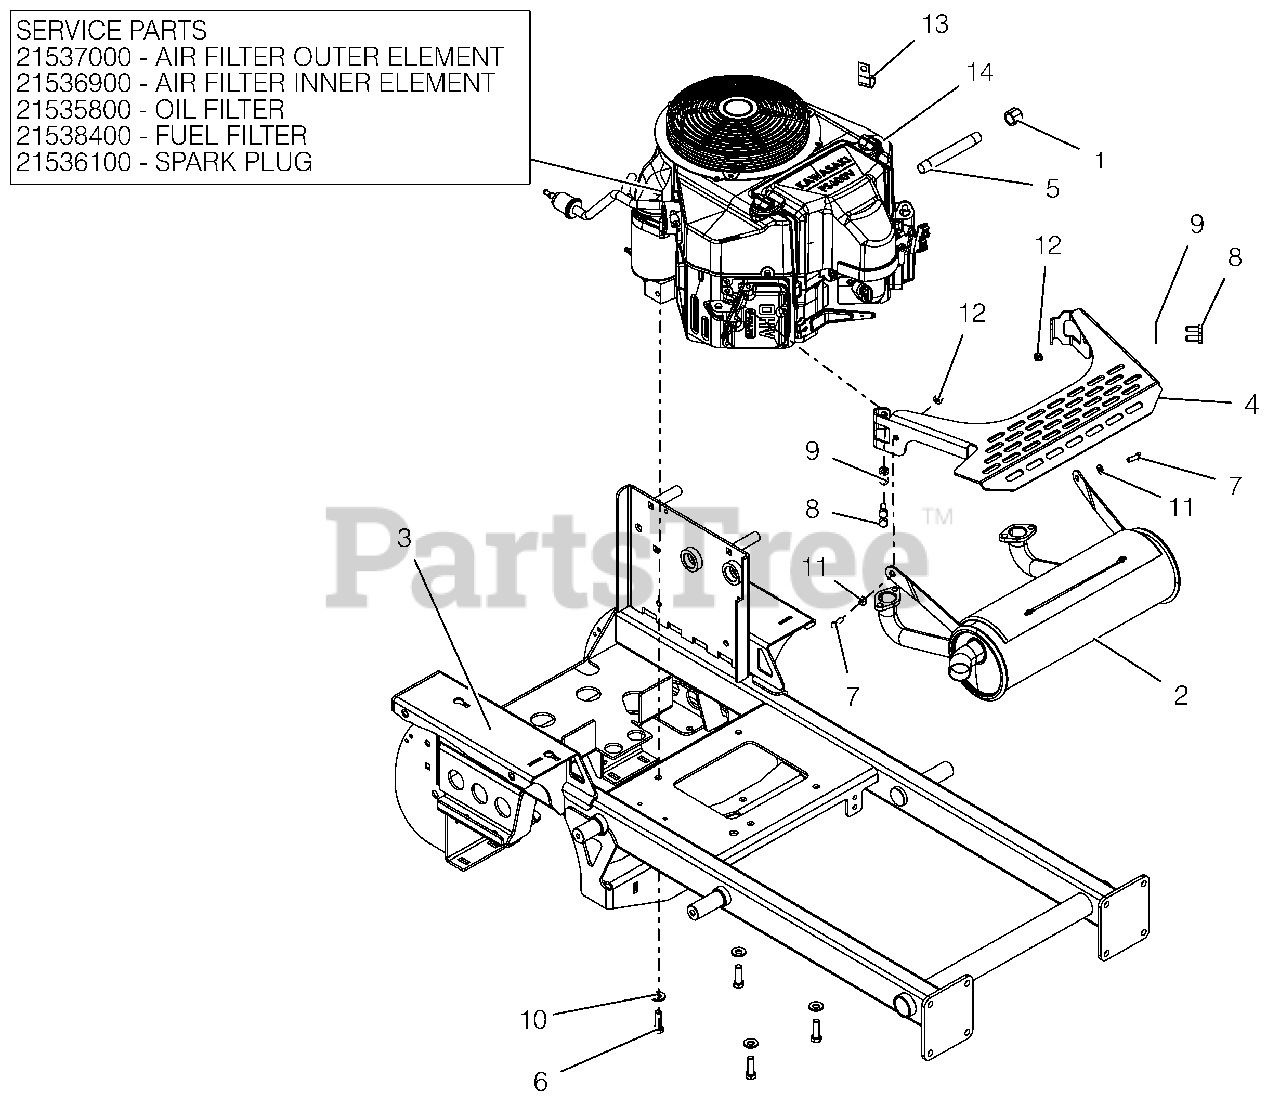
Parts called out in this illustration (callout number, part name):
1	PIPE CAP 3/8 NPT FEMALE
2	MUFFLER, KAW FS PROWALK
3	WLDMT, COMPACT PROSTANCE FRAME
4	SHIELD, MUFFLER
5	PIPE, .375" NPT X 5"
6	BLT-HEX.38-16X1.25 G5YZ NYTORQ
7	@BLT-HEX .25-20X.75 GR5 YWZC
8	@BLT-HEX M8-1.25X20 YWZC
9	@WSHR-LK .31X.078 REG YWZC
10	WASHER, 3/8" SPRING DISC
11	@WSHR-FL-STL.281X.62X.065 YWZC
12	@NUT-LK-NYL-FLG .25-20 YWZC
14	ENG. KAW FS600
14	AIR FILTER, KAWASAKI FR
14	PRE FILTER, KAWASAKI FS
14	FILTER,OIL - KAW
14	FUEL FILTER - KAWASAKI
14	PLUG, SPARK
